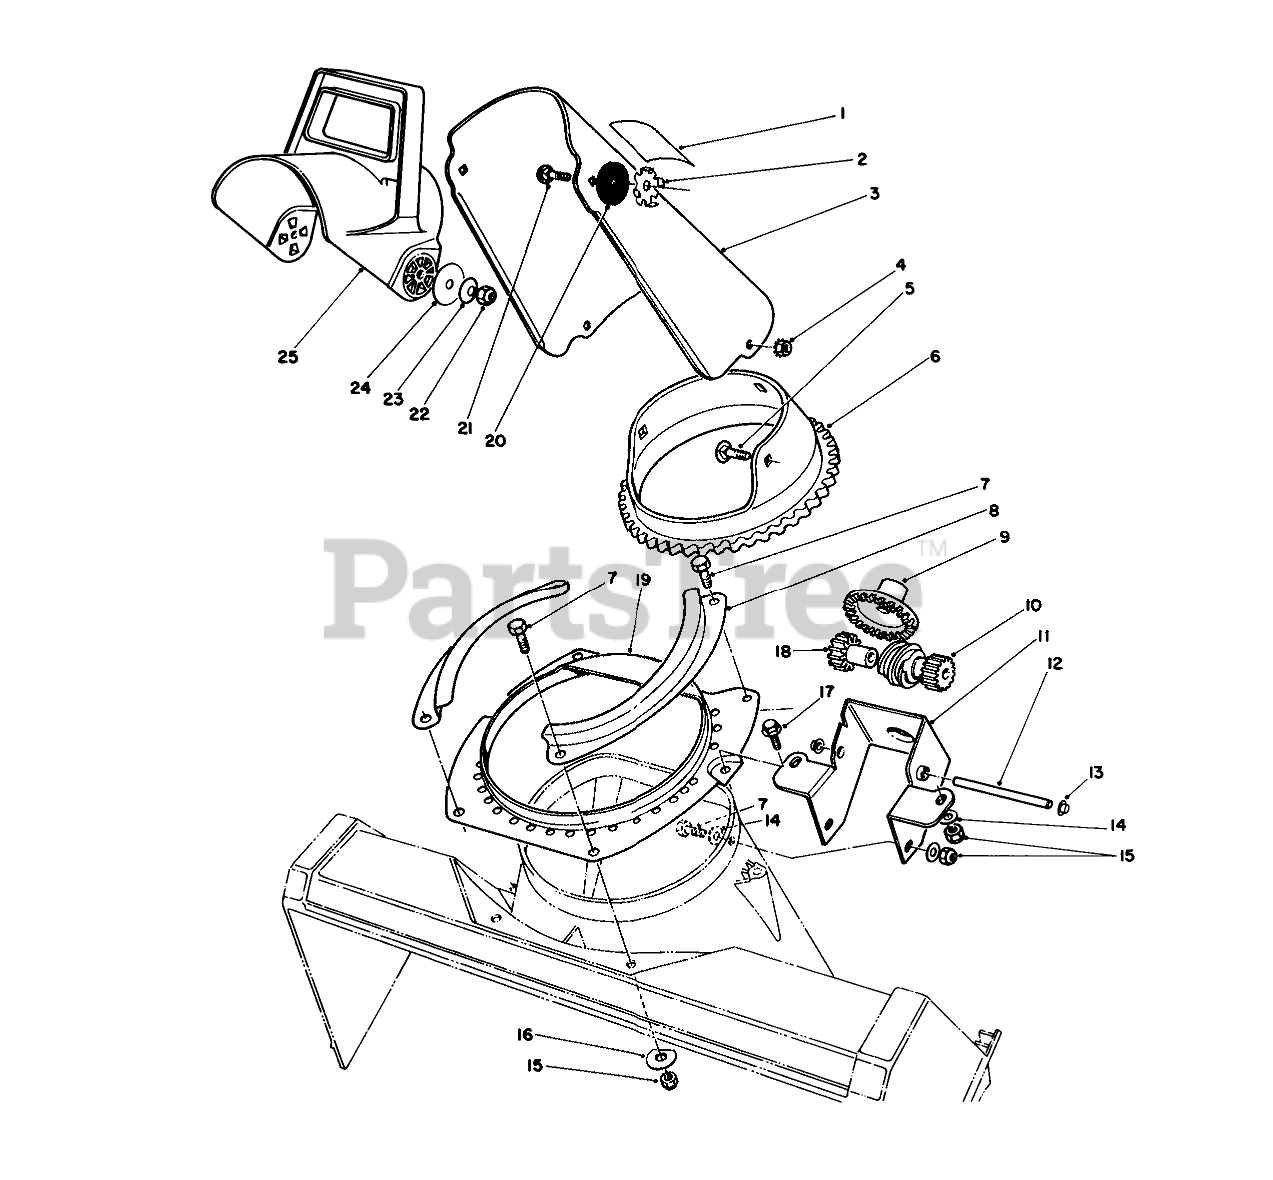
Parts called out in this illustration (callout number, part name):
1	Decal-Discharge
2	PLATE-FRICTION
3	Chute-Discharge (Incl. Ref. #1)
4	NUT-KEPS
5	SCREW-CARR
6	RING-GEAR, CHUTE
7	SCREW-HH
8	Retainer-Chute Ring
9	GEAR-FACE
10	GEAR-SPUR/WORM
11	Bracket-Chute Gears
12	SHAFT-GEAR, WORM
13	NUT-PUSH
14	WASHER-FLAT
15	NUT-LOCK, NI
16	Washer
17	SCREW-PLASTITE
18	GEAR-SPUR, SPACER
19	Ring-Chute Support
20	WASHER-RUBBER
21	SCREW-CARR
22	NUT-LOCK, NI
23	WASHER-BELLEVILLE
24	WASHER-FLAT
25	CHUTE-DEFLECTOR
